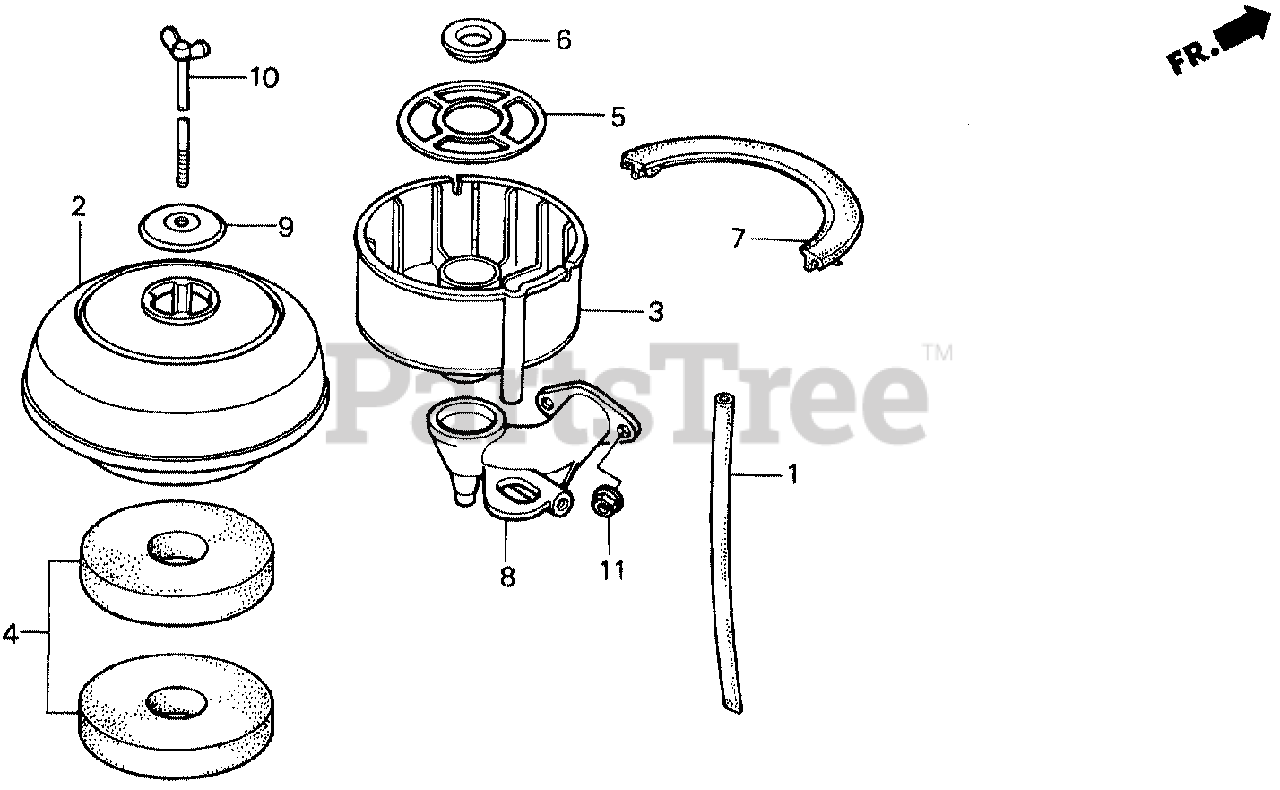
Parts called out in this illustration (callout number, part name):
1	TUBE, BREATHER
2	BODY, CLEANER
3	PAN, AIR CLEANER OIL
3	PAN, AIR CLEANER OIL (NA USE ALT:17402-841-000)
4	ELEMENT, AIR CLEANER
5	GRID, AIR CLEANER
6	COLLAR, AIR CLEANER
7	GASKET, OIL CLEANER
8	ELBOW, AIR CLEANER
9	CAP, AIR CLEANER
10	BOLT, AIR CLEANER
11	NUT, FLANGE (6MM)
